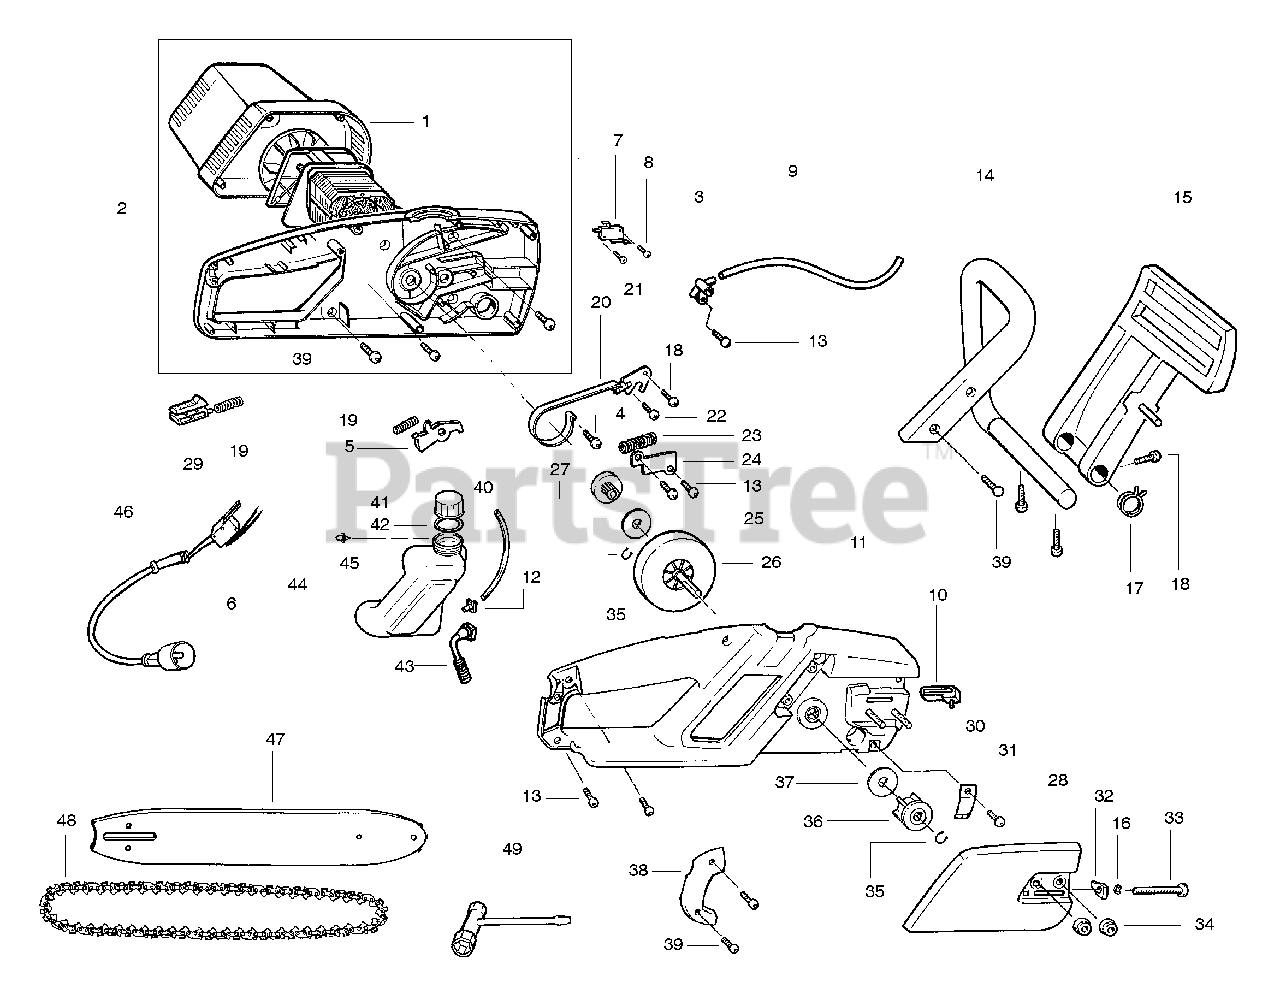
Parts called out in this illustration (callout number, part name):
1	Motor Cover
2	Housing/Motor Ass'y.
3	Oil Pump Ass'y.
6	Switch-Momentary
7	Switch-Chain Brake
8	Screw
9	Outlet Line
10	Insert Bar Pad
11	Housing Cover
12	Oil Pickup Fitting
14	Front Handle
15	Handguard
16	Retainer-Bar Adjust
17	Spring-Handguard
18	Screw-Pivot
19	Spring-Trigger
20	Brake Band
21	Front/Rear Link Ass'y.
22	Screw
23	Spring-Brake
24	Cover Spring
25	Washer-Thrust
26	Gear Drive
28	Bar Clamp
29	Lockout Button
30	Chain Catcher
32	Pin-Bar Adjust
33	Screw-Bar Adjust
34	Nut-Bar Mounting
35	Ring-Retainer
36	Sprocket (3/8 Pitch)
37	Washer-Sprocket
38	Cover-Access
40	Inlet Line
41	Oil Cap
42	O-Ring (Oil Cap)
43	Oil Pickup Ass'y.
44	Check Valve (Duckbill)
45	Oil Tank Ass'y.
46	Cord Set
48	Chain 16"
49	Bar Wrench
